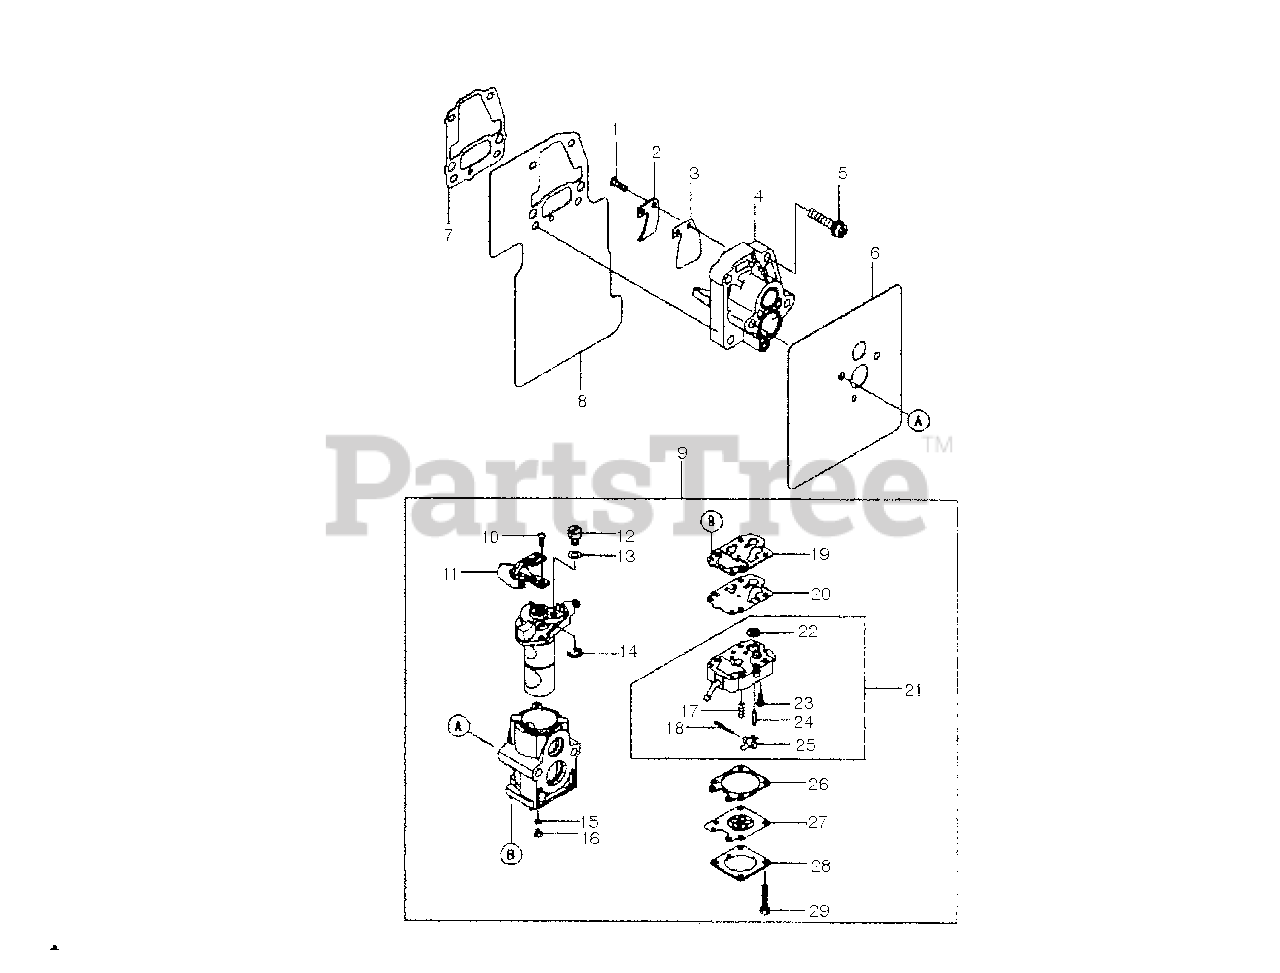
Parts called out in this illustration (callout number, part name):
1	SCREW 3 X 12
3	VALVE REED
4	INSULATOR
5	SCREW 5 X 25
6	GASKET CARBURETOR/INSULATOR
7	GASKET INSULATOR
9	CARBURETOR ASSY
14	RING SNAP
16	JET MAIN #56
20	DIAPHRAGM
24	VALVE-FLOAT KAAZ # ELX
27	DIAPHRAGM
